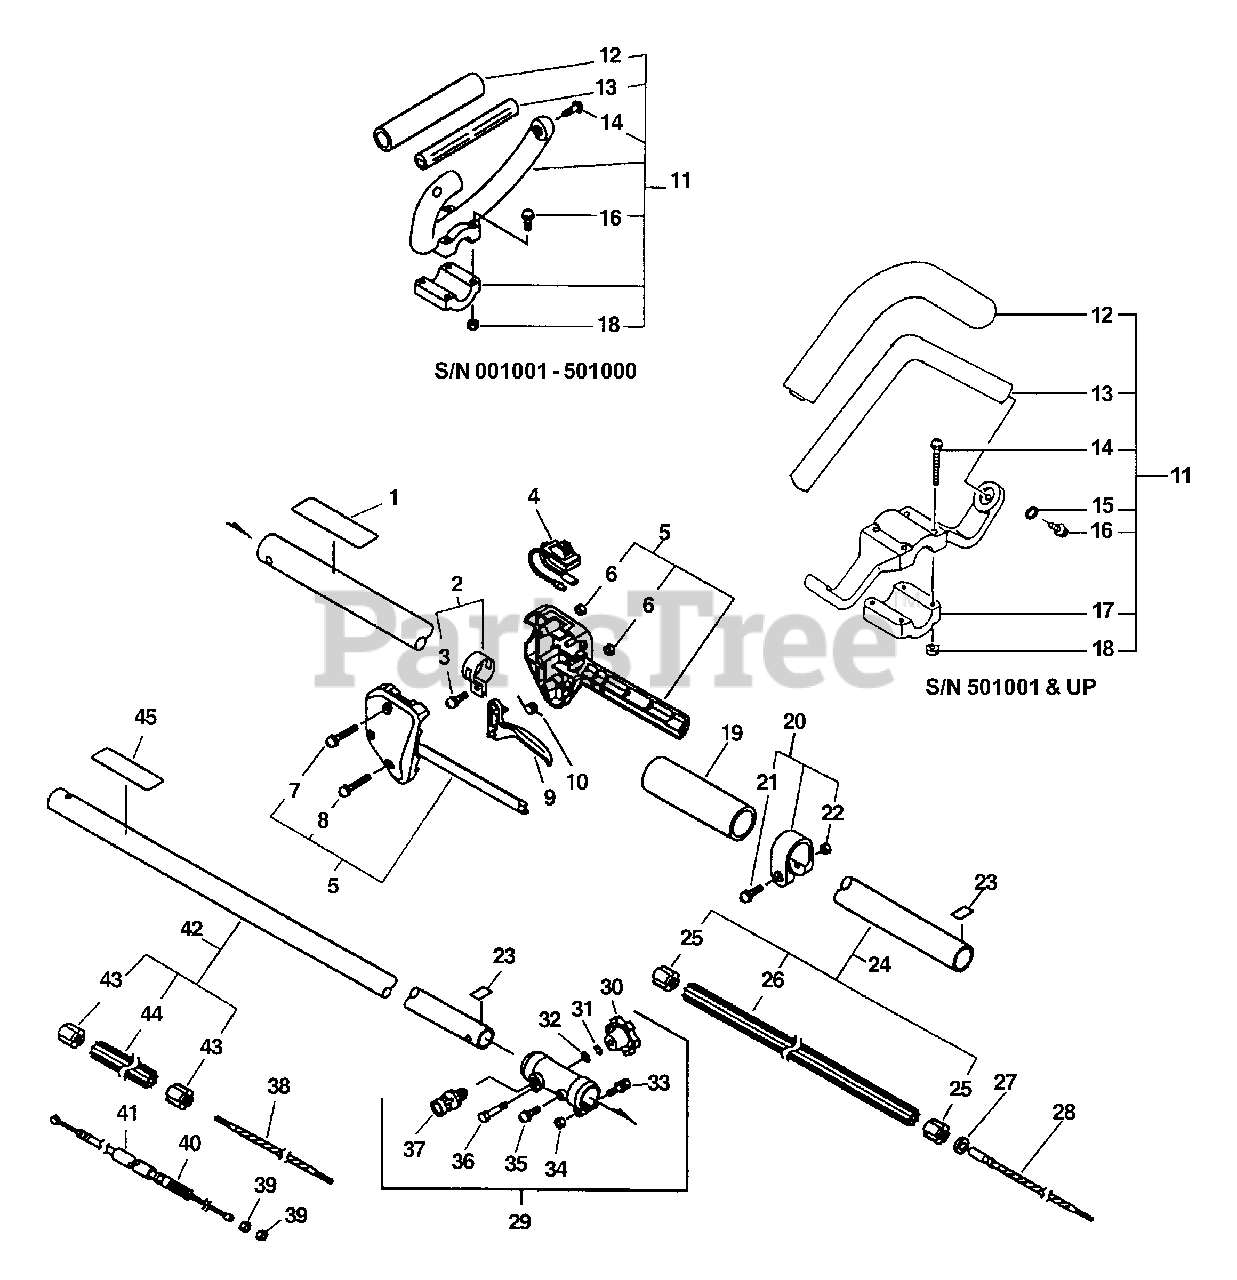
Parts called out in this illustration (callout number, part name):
1	LABEL - CAUTION
2	CLAMP KIT
3	SCREW - 5X14
4	IGNITION SWITCH ASSY
5	CONTROL HANDLE KIT
7	SCREW - 5X35
8	SCREW - 5X25
9	TRIGGER, THROTTLE
10	SPRING, TRIGGER
11	LOOP HANDLE ASSY
11	HANDLE ASSY - FRONT
12	GRIP, HANDLE
13	HANDLE - FRONT
14	SCREW - 5X30
14	SCREW - 5X35
16	SCREW - 5X35
16	SCREW - 5X20
17	BRACKET, HANDLE - LOWER
19	GRIP, HANDLE
20	CLAMP KIT
21	SCREW - 5X28
23	LABEL - ALIGNMENT
24	MAIN PIPE ASSY
26	LINER - FLEXIBLE
28	DRIVESHAFT - FLEXIBLE -- UPPER
29	COUPLER ASSY
30	KNOB, FASTENER
31	LOCKWASHER - 5
32	WASHER - 5
33	SCREW - 5X30
35	SCREW - 5X12
36	BOLT - 5X35
37	LATCH ASSY
38	DRIVESHAFT - FLEXIBLE
40	CABLE, THROTTLE
41	TUBE - VINYL
42	MAIN PIPE ASSY
44	LINER - FLEXIBLE
45	LABEL - CAUTION
